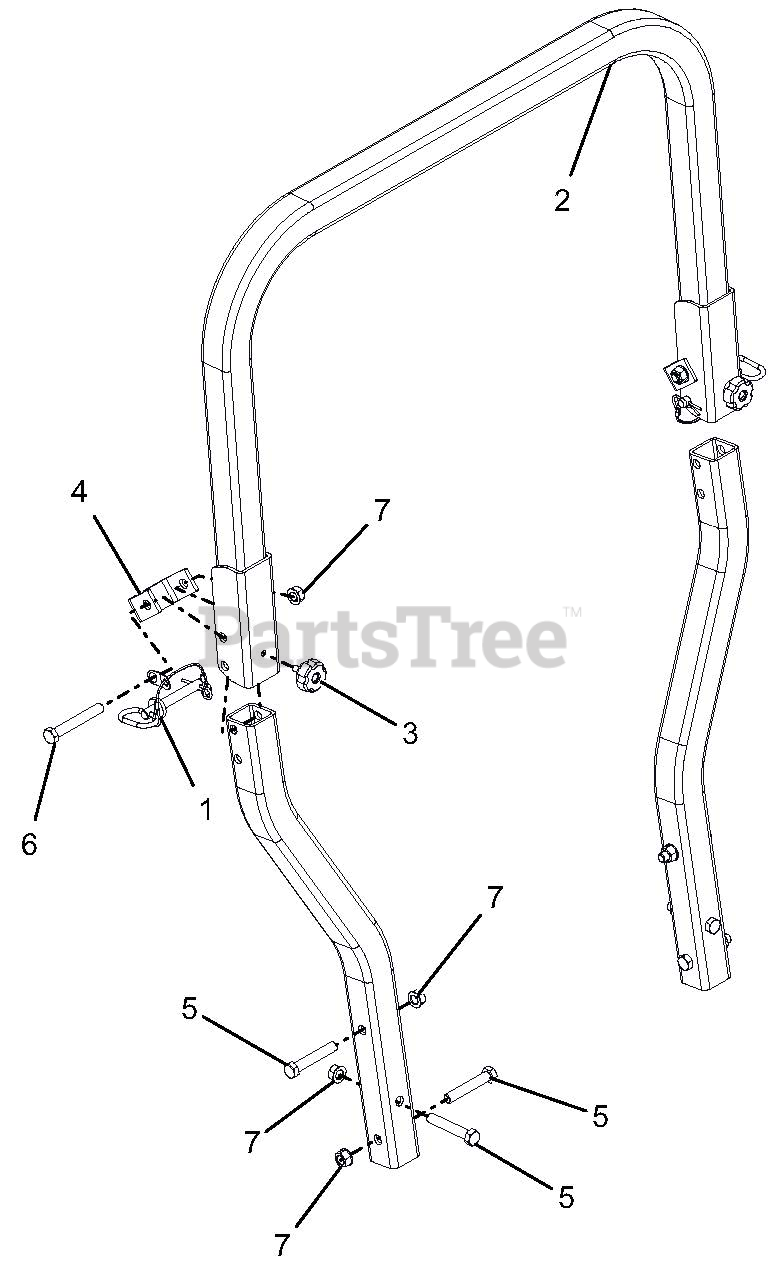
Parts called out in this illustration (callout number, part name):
1	ASSY, ROPS PIN/LANYARD
2	ROPS INCLUDES HOOP RH AND LH SUPPORT
3	KNOB, ROUND 5/16-18 X .750
4	BRKT, ROPS STOP
5	BLT-HEX .50-13X3.00 GR5 YWZC
6	BLT-HEX .50-13X3.50 GR5 YWZC
7	NUT, LK-TOP-FLG .50-13 YWZC
